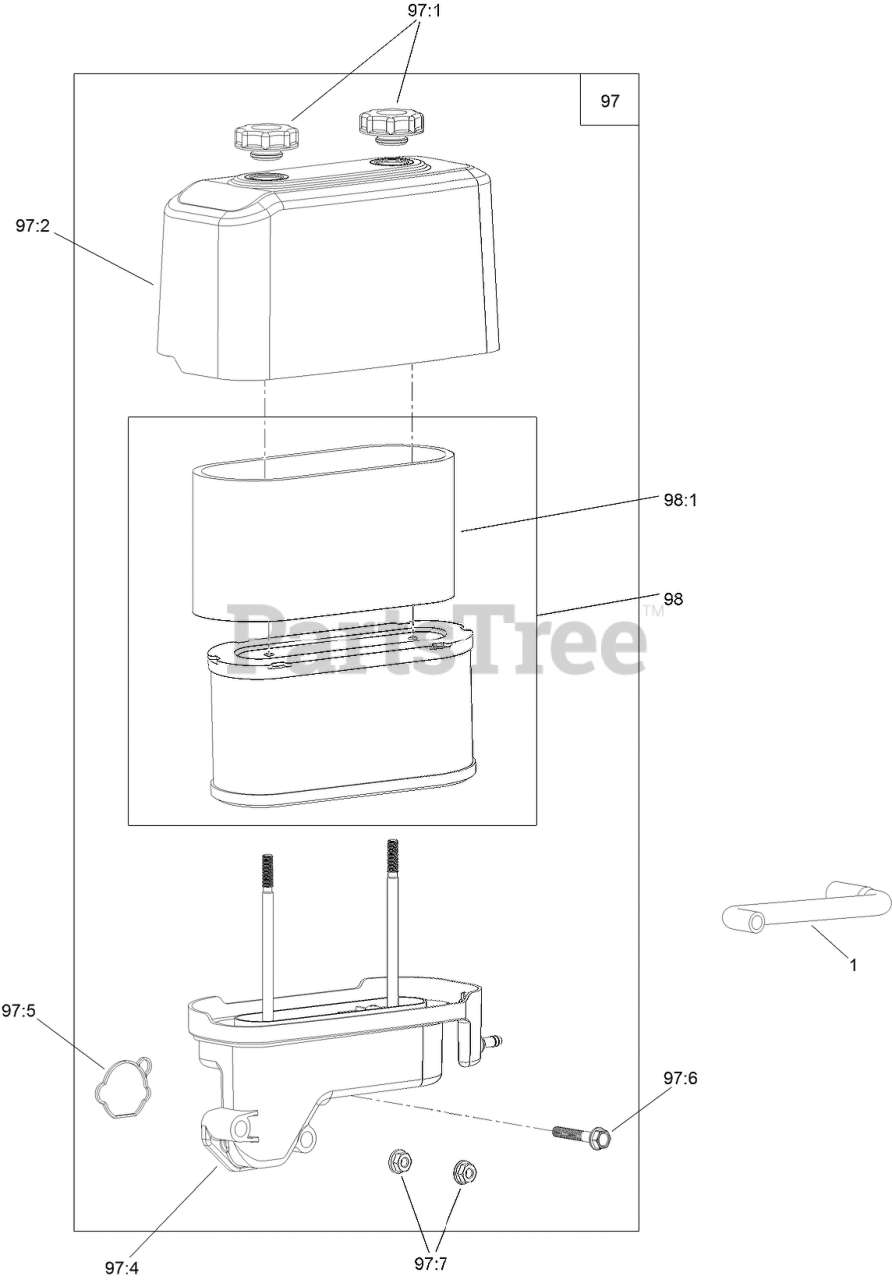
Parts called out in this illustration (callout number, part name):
1	TUBE-BREATHER
97	AIR FILTER ASM
97:1	NUT-SPEED
97:2	COVER-FILTER, AIR
97:5	GASKET-CARBURETOR
97:6	SCREW-HHF
97:7	NUT-FLANGE
98	AIR FILTER KIT
98:1	PREFILTER
